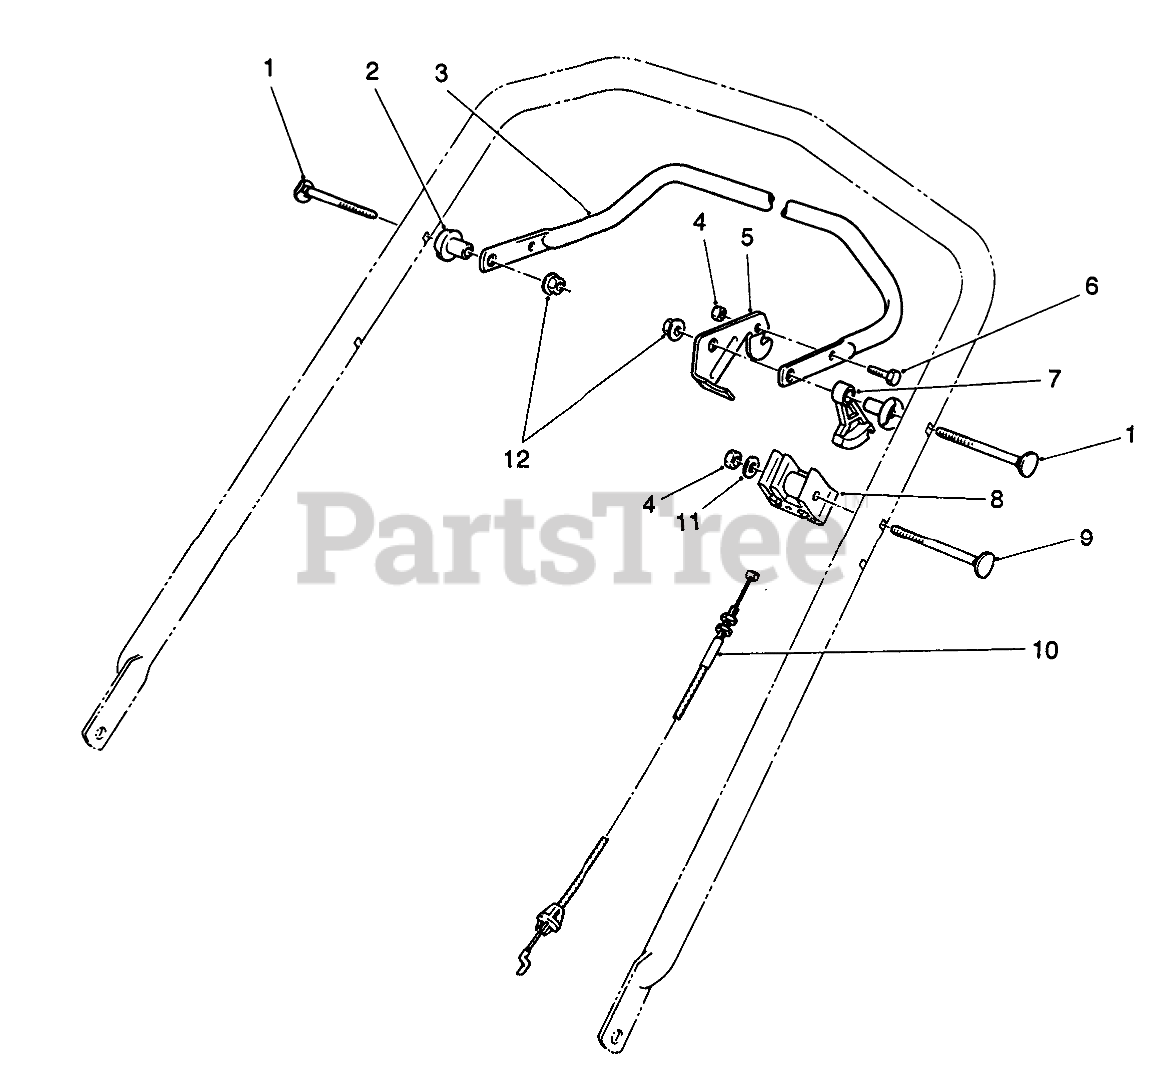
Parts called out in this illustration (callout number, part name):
1	SCREW-HANDLE
2	SPACER-SUPPORT
3	Bar-Control
4	NUT-LOCK, NI
5	CONTROL LEVER
6	SCREW-HH
7	LEVER-TRACTION
8	SUPPORT-CABLE
9	SCREW-HANDLE
10	TRACTION CABLE
11	WASHER-FLAT
12	NUT-LOCK, NI
